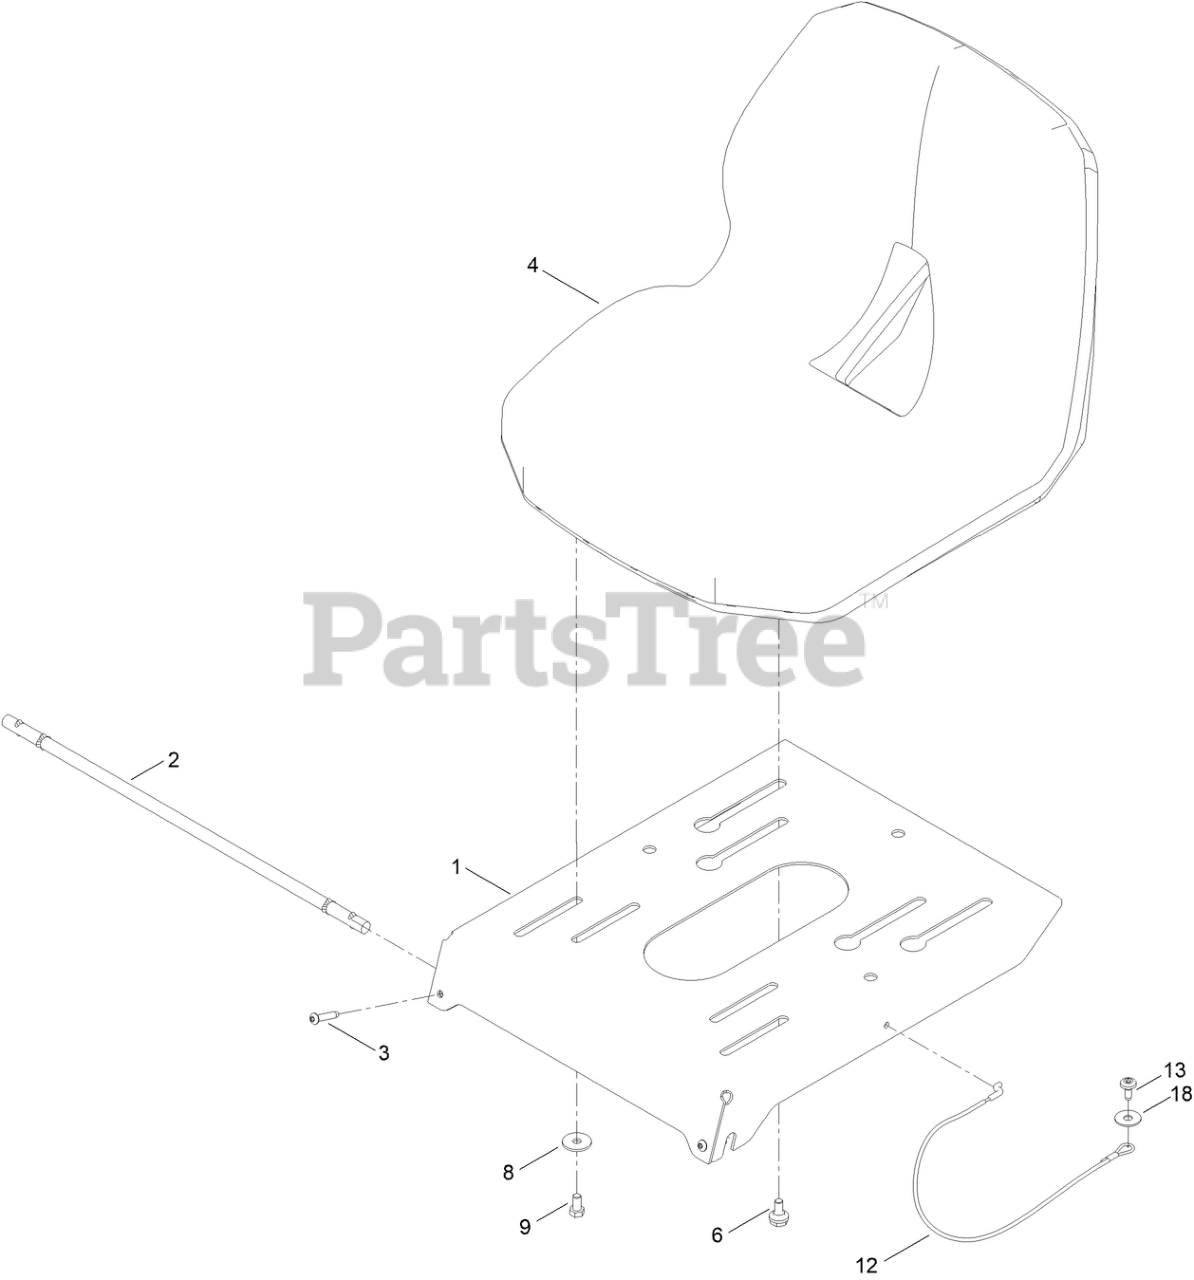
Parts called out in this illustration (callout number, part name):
1	PAN-SEAT
2	ROD-PIVOT
3	SCREW-TTH, THREAD ROLLING
4	SEAT-16 IN
6	BOLT-SHOULDER,HFH
8	WASHER-PIVOT
9	SCREW-HH
12	CABLE-LANYARD
13	SCREW-SHOULDER
18	WASHER-FLAT
